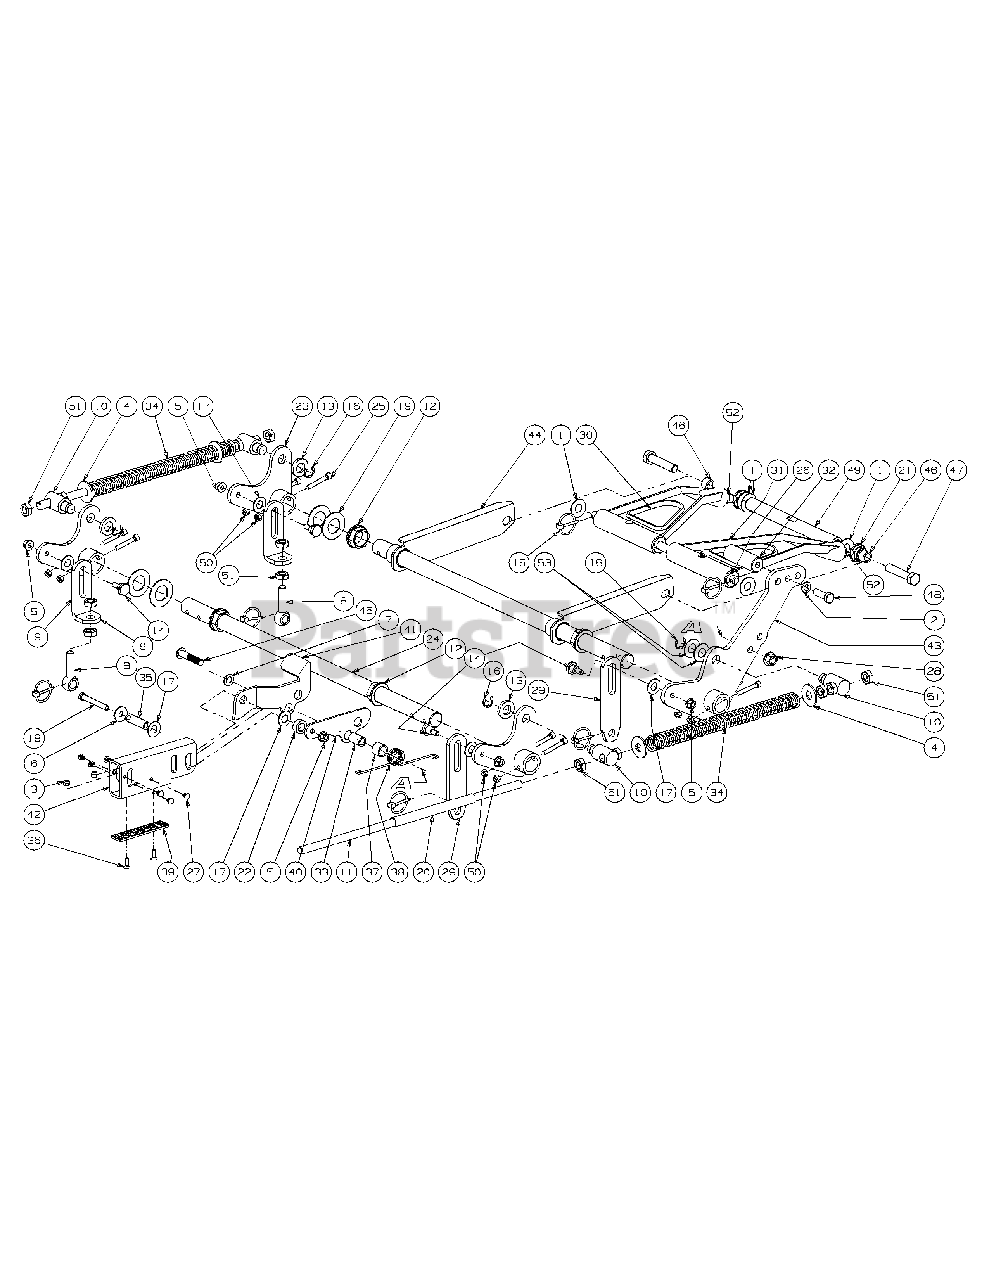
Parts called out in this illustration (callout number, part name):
1	Washer, 1.5 x .655 x .055
2	Lock Washer, 1/2
3	Lock Nut w/Nylon Insert
4	Flat Washer, 5/8
5	Hex Nut, Flange Lock, 3/8-16
6	Flat Washer, 1.25 x .411 x .100
7	Flat Washer, .536 ID x .930 OD x .05
8	Eye Bolt, 5/8ID
9	Eye Bolt Mount Link, 5/8 ID
10	Ferule Lift
11	Lift Connector Rod
12	Hex Flange Bearing, 1.25 ID
13	Spacer, .812 ID x .268 Lg.
14	Shoulder Screw, 0.625 OD x .437 Lg.
15	Linch Pin, 3/16 Dia.
16	E Clip, 3/4 Dia.
17	Nylon Flat Washer, 5/8
18	HHCS, 3/8-16, 3.00
19	Flat Washer, 1.25 ID
20	Hose, 5/8 ID 13/16 OD, 8" LG
21	Rod End, Male
22	Spacer, .630 ID x 1.06 OD x .440
23	Bellecrank Weldment Assembly
24	Deck Lift Shaft
25	Socket Head CapScrew, 5/16-18 x 2
26	Lift Link Rod
27	Rivet, 1/4 x 5/8
28	Nut, 1/2-13, FlangeLock
30	Bearing Lift Brace Assembly, Left Hand includes:
30	Grease Fitting
31	Bearing Lift Brace Assembly, Right Hand includes:
31	Grease Fitting
32	Deck Lift Foot Pedal
33	Spacer, .51 ID x .75 OD x 1.240
34	Lift Compression Spring
35	Spacer, .375 ID x .625 OD x 2.20
36	Flat Head Cap Screw, 1/4-20 x .75
37	Spacer, .76 ID x 1.0 OD x .75
38	Torsion Spring, .120 Wire x 1.32 OD
39	Lift Wear Plate
41	Lift Link Bracket
42	Lift Tube, 3.0 x 1.5
43	Deck Lift Foot Pedal Weldment
44	Front Frame Strut Assembly
45	Socket Head Cap Screw, 1/2-13 x 2.50
46	Spacer, .632 x .877 x .548
47	HHCS, 5/8-11 x 3.00
48	Hex Cap Screw, 1/2-13 x 1.50
49	Front Lift Link Shaft, Threaded
50	Nut, 5/16-18, Nylock
51	Jam Nut, 5/8-11
52	Jam Nut, 5/8-18
53	Washer, .76 x 1.49 x .06
